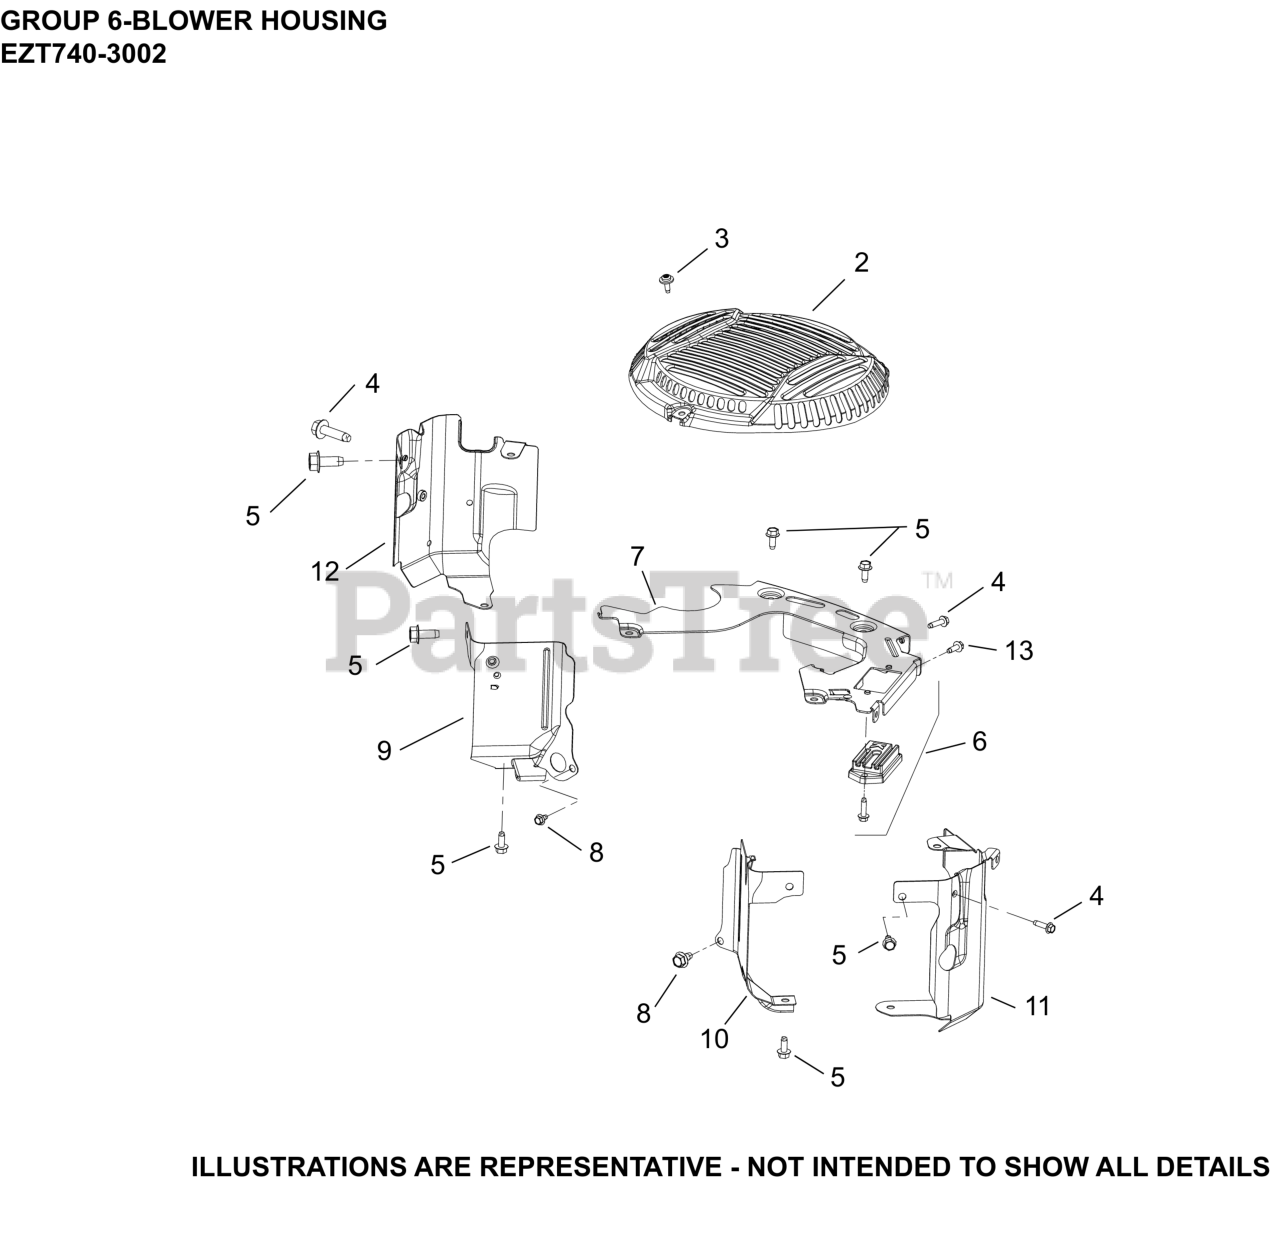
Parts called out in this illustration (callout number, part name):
2	GUARD, GRASS SCREEN (METAL)
3	SCREW, SEMS
4	SCREW, THD FRM-USE 25 086 473-S
5	SCREW, THREAD FORMING
6	PLATE ASSEMBLY, BACKING (15A)
7	PLATE, BACKING
8	SCREW, THREAD FORMING
9	BAFFLE, VALLEY #1
10	BAFFLE, VALLEY #2
11	BAFFLE, LEFT BARREL
12	BAFFLE, RIGHT BARREL
13	SCREW, THREAD FORMING
NI	KIT, BLOWER HOUSING
